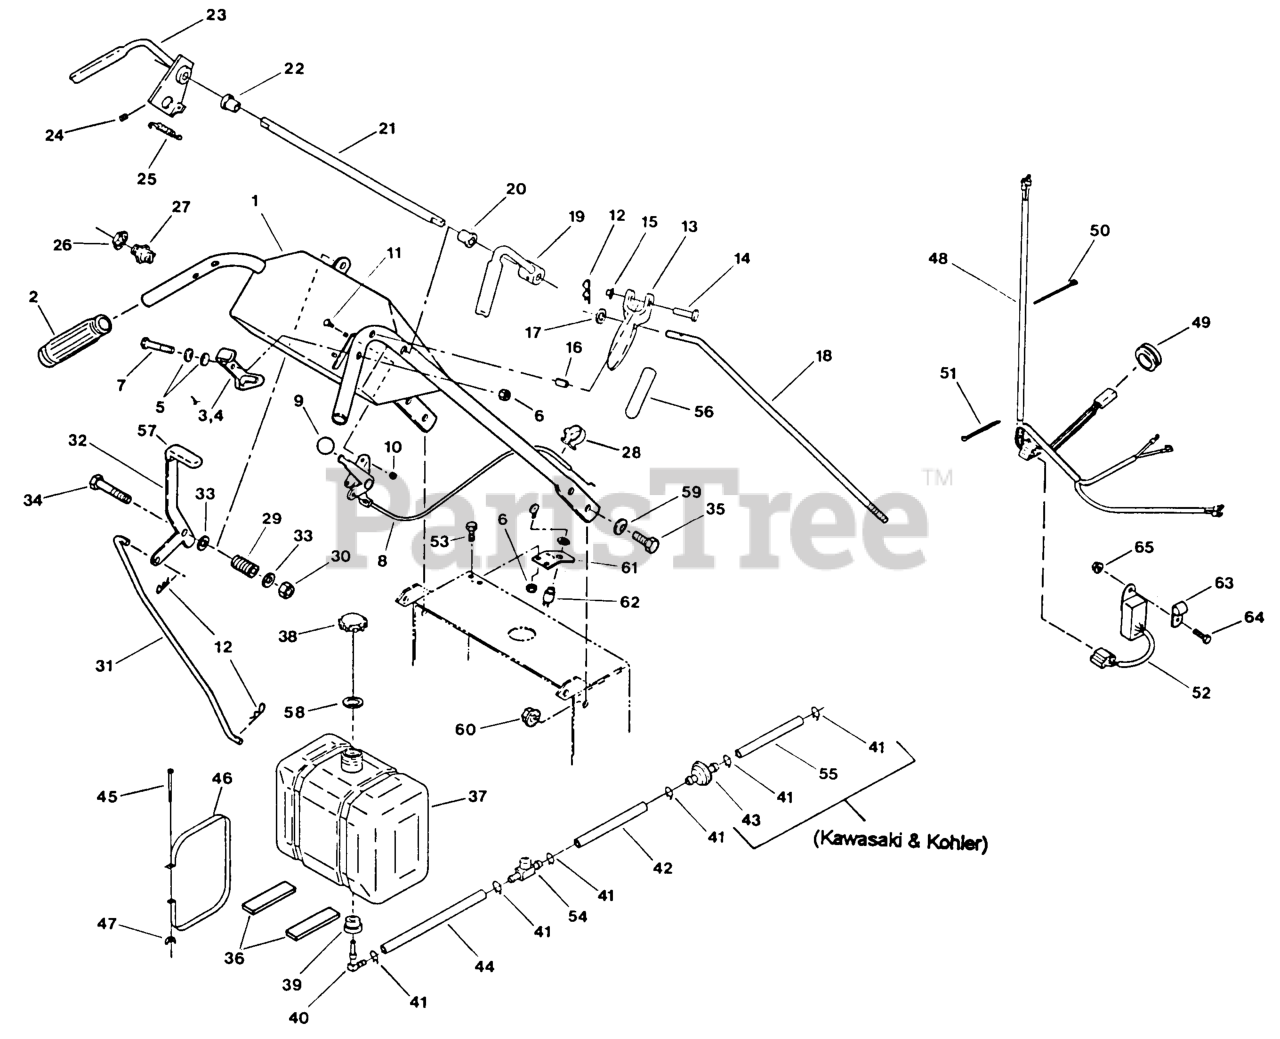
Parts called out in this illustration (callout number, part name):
3	LATCH,W/GRIP RH
4	LATCH,W/GRIP LH
5	WASHER-SPRING
8	CABLE-CONTROL, THROTTLE
9	KNOB-BALL
11	BOLT-CARR
12	PIN-COTTER
13	DRIVE LEVER ASM
14	PIN-LEVER, DRIVE
15	NUT-PUSH
16	PIN-ROLL
20	BUSHING-NYLON
21	ROD,CONNECTING
22	BUSHING,FLANGED
24	PRO-LOCK,NUT TYPE
25	SPRING-EXTENSION
27	SWITCH,OPERATOR CNTRL
28	CLIP-CABLE
29	SPRING-COMPRESSION
31	LINKAGE-BLADE, UPPER
36	PAD,PLASTIC TANK
38	CAP-FUEL
40	ELBOW-TANK, FUEL
41	CLAMP
42	HOSE-LINE, FUEL
44	HOSE-FUEL
45	SCRW,MACH CRPH
47	WINGNUT
48	HARNESS,WIRING KAW METRO
49	GROMMET
50	TIE-PLASTIC
51	TIE-CABLE
54	VALVE-FUEL
55	HOSE-LINE, FUEL
56	GRIP-LEVER, DRIVE
57	GRIP-LEVER
58	GASKET-CAP, TANK
62	SWITCH & KEY (INCLUDES NU
63	CLIP-LOOM
